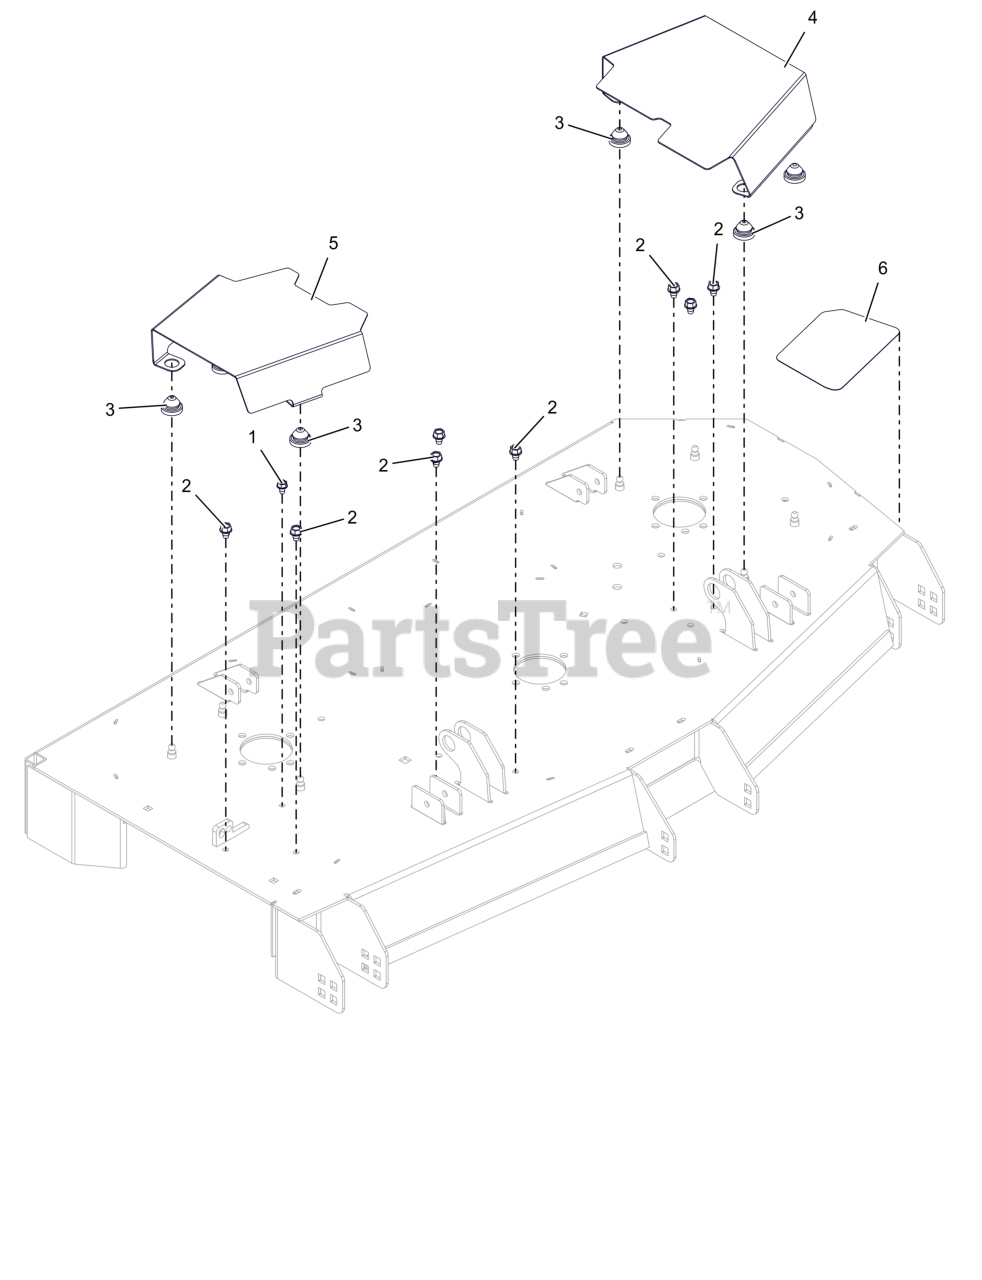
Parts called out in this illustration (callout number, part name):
1	SCR,TAP .312-18X.50 HWH TR ZCC
2	SCR,TAP .375-16X.50 HWH TR ZCC
3	COUPLING, RUBBER PUSH-IN
4	COVER- BELT 52" LEFT
5	COVER- BELT 52" RIGHT
6	GRIP, STEP ANTI SKID HD XF3
